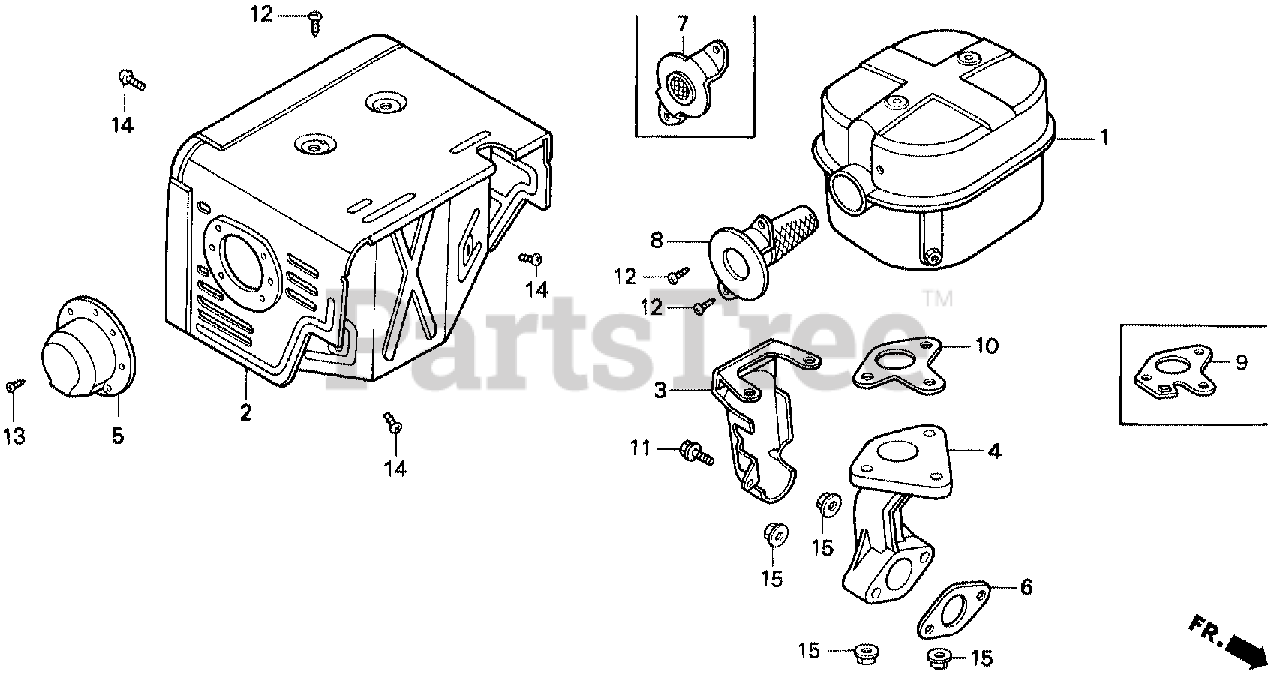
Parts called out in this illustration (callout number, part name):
1	MUFFLER
2	PROTECTOR, MUFFLER
4	PIPE, EX.
6	GASKET, EX. PIPE
6	GASKET, EX. PIPE (WACKER)
7	FLANGE, BAFFLE
8	ARRESTER, SPARK
9	GASKET, MUFFLER (ARRESTER)
10	GASKET, MUFFLER
12	SCREW, TAPPING (5X8)
14	SCREW, PAN (6X6)
15	NUT, FLANGE (8MM)
